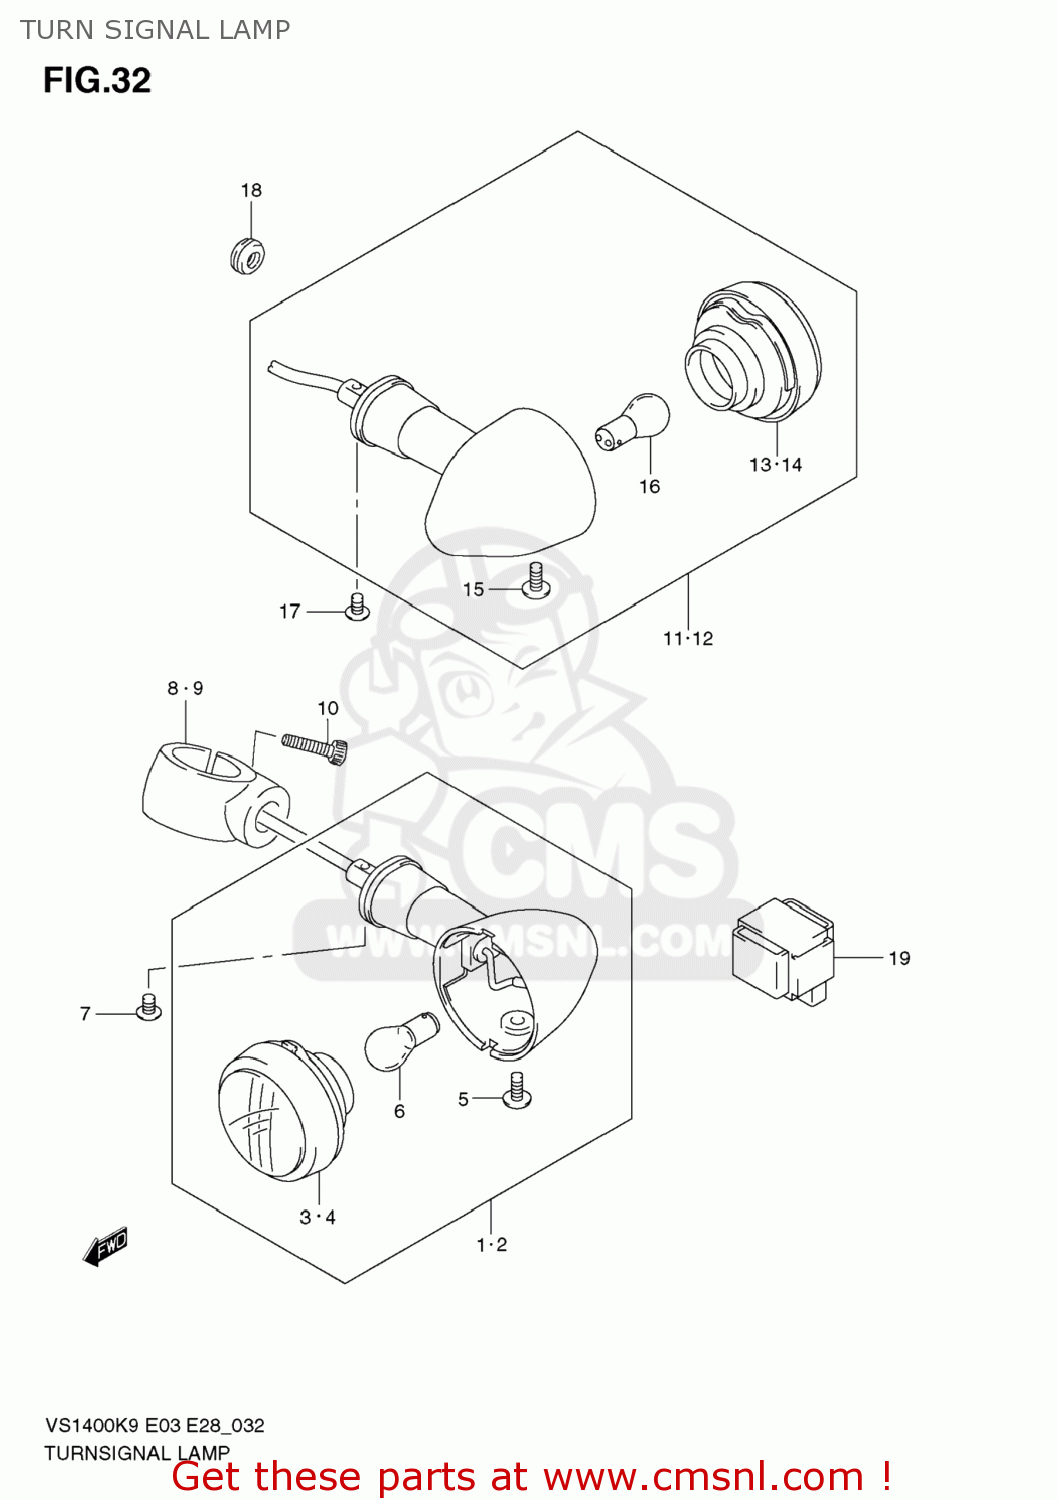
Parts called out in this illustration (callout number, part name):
1	LAMP ASSY,FR TURN SIGNAL,R
2	LAMP ASSY,FR TURN SIGNAL,L
3	LENS
4	LENS
5	SCREW(4X10)
6	BULB(12V21/5W)
7	SCREW
8	BRACKET,FR TURNSIGNAL LAMP,R
9	BRACKET,FR TURNSIGNAL LAMP,L
10	BOLT
11	LAMP ASSY,RR TURNSIGNAL,R
12	LAMP ASSY,RR TURNSIGNAL,L
13	LENS
14	LENS
15	SCREW(4X10)
16	BULB(12V21W)
17	SCREW
18	GROMMET
19	RELAY ASSY
